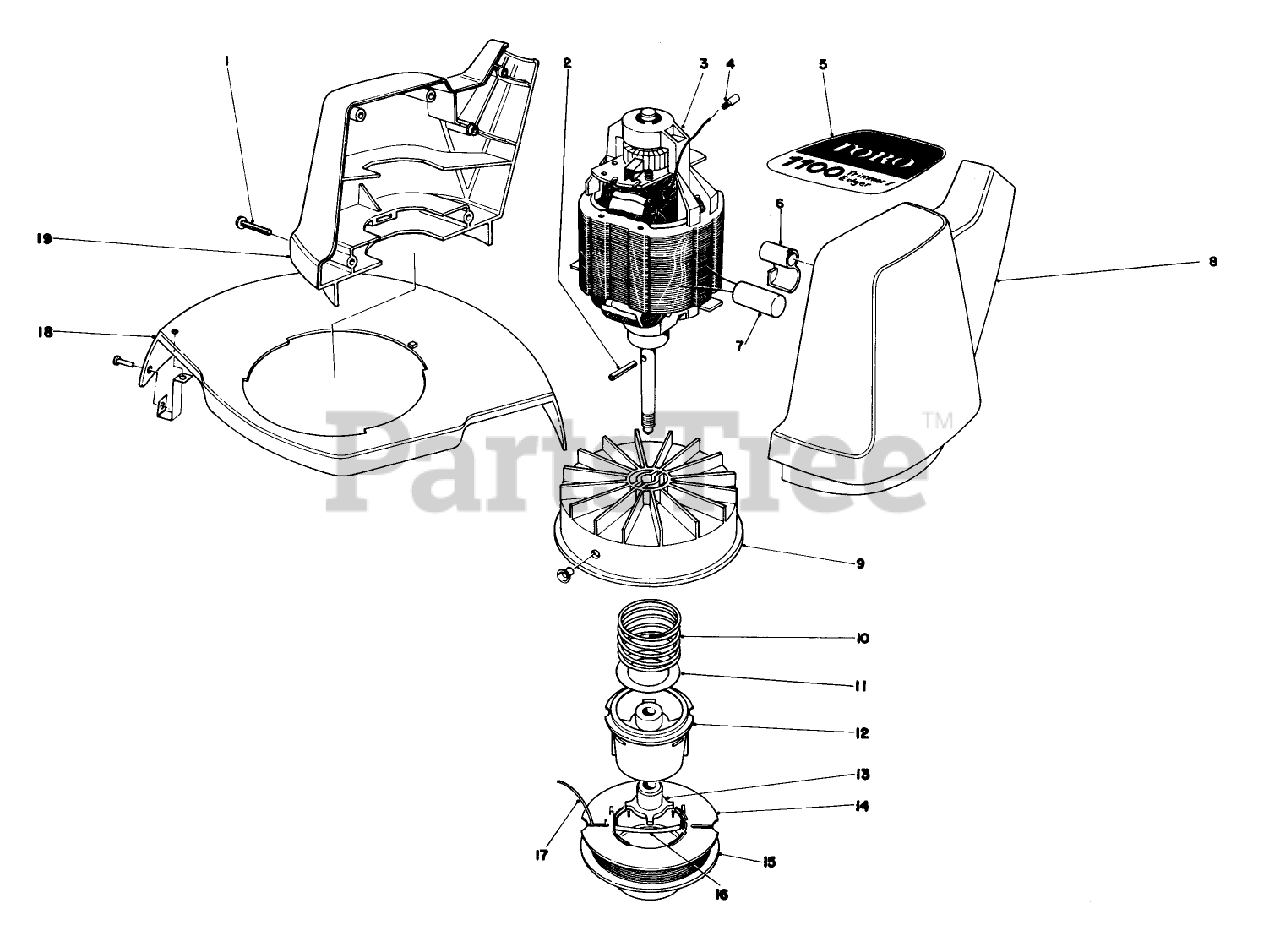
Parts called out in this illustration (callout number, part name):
1	Screws
2	COIL PIN
3	Motor
4	CONNECTOR WIRE JOINT
5	DECAL - TORO 1100
6	Clamp-Suppressor
7	Suppressor
8	Left Motor Housing
9	DRUM W/EYELET
10	SPRING COMPRESSION
11	WASHER-FLAT
12	SPOOL CORE
13	Driver
14	Empty SPooI
15	Cutting Line (50 .065" Dia.)
16	SADDLE-SPOOL CAP
17	LINE-FILIMENT
18	Shield with Cut Off Blade
19	Right Motor Housing
